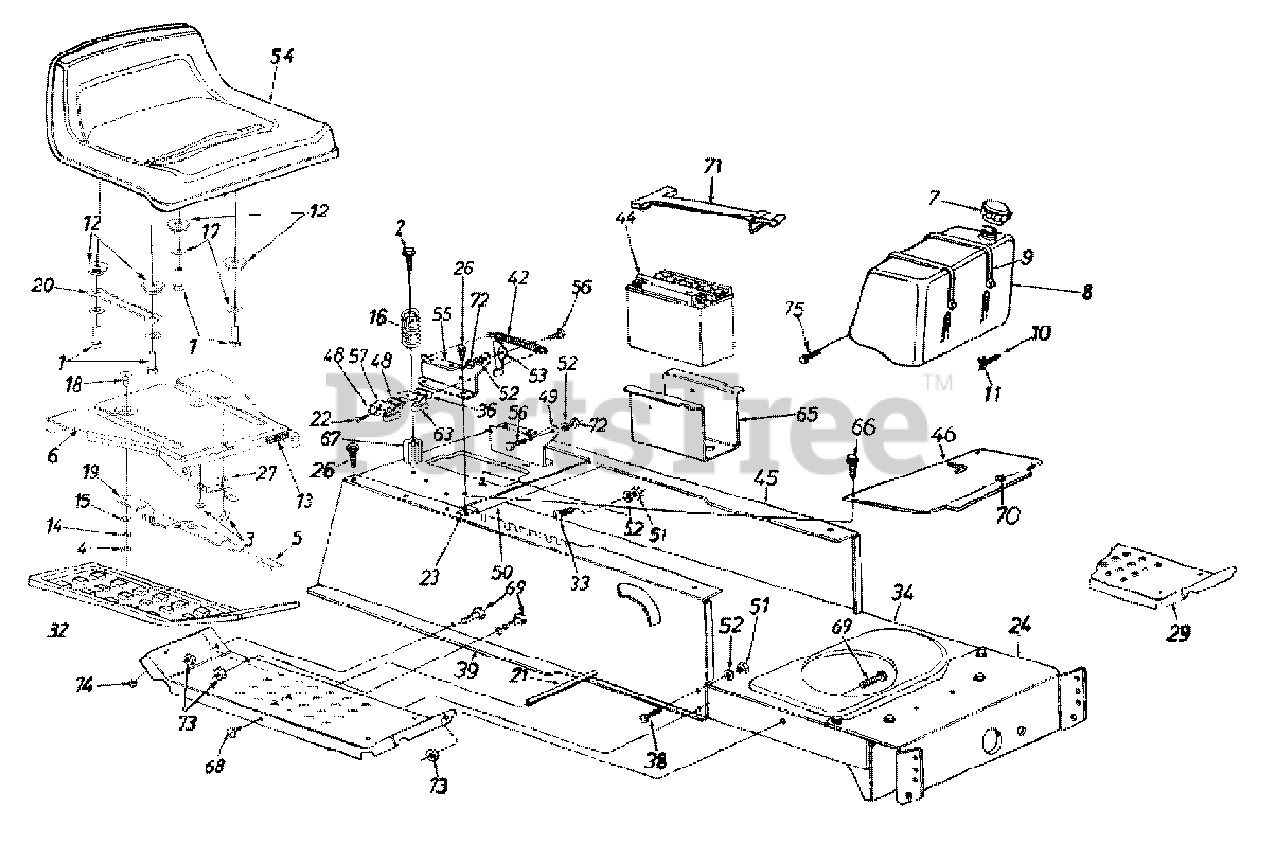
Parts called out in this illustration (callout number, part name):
1	Hex Cap Scr. 3/8-16 x 1.0" Lg.
2	Hex Wash. Hd. Tap Scr. 5/16-18 x 3.25" Lg.
3	Hx Scr. B-Tap Wash. #10-16: .38 Lg.
4	Lock Nut 1/4-20
5	Grip
9	Tie Strap
10	Fuel Line
12	Seat Spacer
13	Compression Spring
14	Wash. Spring .265 x .562 x .025
15	Fl. Wash. .344 ID x .62 OD x .03
16	Compression Spring
17	Fl. Wash. .406 ID x .875 OD x .059
18	Shldr. Scr. .340 x .285 - 1/4-20
20	Seat Selector
21	Running Board Rod
22	Hex AB-Tap Scr. #8 x .50"
23	Speed Nut #10Z
26	Hex Wash. Hd. AB-Tap Scr. 5/16 x .75" Lg.
33	Truss Mach. Scr. 5/16-18 x .75" Lg.
36	Insulator Boss Plate
38	Hex Bolt 5/16-18 x .75" Lg.
44	12-V Battery
52	L-Wash. 5/16" I.D.
53	Seat Lift Brkt.
54	Seat
56	Shld. Bolt .437" Dia. x .268"
57	Spring Switch
63	Safety Switch (Seat)
66	Truss Mach. B-Tap Scr. #10 x .5" Lg.
67	Spring Spacer
68	Pan Hd. Scr. 5/16-18 x .75" Lg.
69	Hex Bolt 5/16-18 x .75" Lg.
70	Snap Bushing
71	Battery Retainer Strap
72	Hex Nut 5/16-18 Thd. (Gr. 5)
73	Hex Sems Nut 5/16-18 Thd.
74	Hex Sems Nut 1/4-20 Thd.
75	Hex Screw 12-24 x .62
